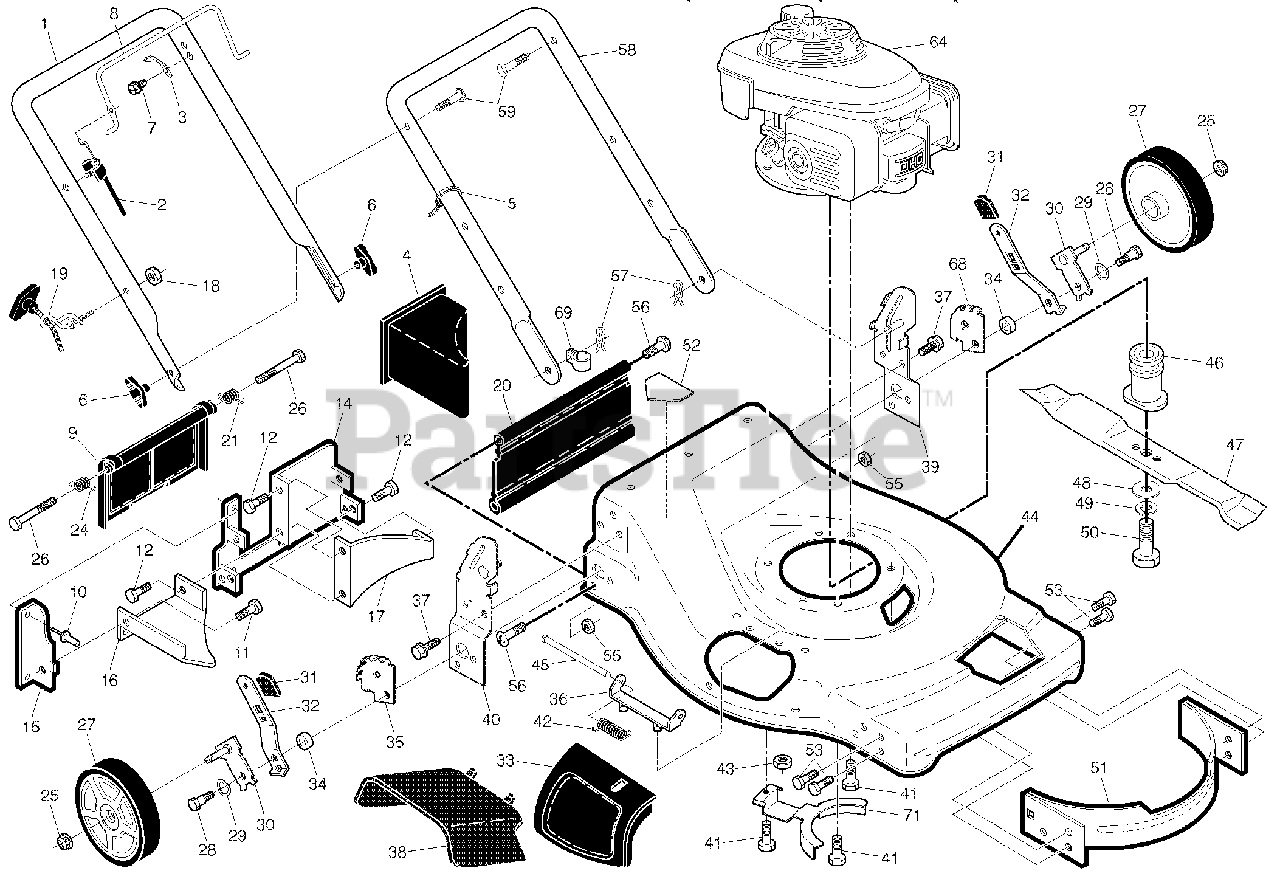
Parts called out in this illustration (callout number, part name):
1	UPPER HANDLE
2	Engine Zone Control Cable
3	Bracket, Upstop
4	MULCH PLUG
5	Wire Tie
6	Handle Knob
7	Hex Washer Head Screw
8	CONTROL BAR
9	Rear Door Assembly
10	Pop Rivet
11	Screw, Self-Tapping
12	SCREW, SEMS, HEX HEAD 1/4-20 X
14	Back Plate
15	Side Baffle
16	Discharge Baffle
17	Rear Baffle
18	Nut, Hex
19	Rope Guide
20	REAR SKIRT
21	Spring, Rear Door, LH
24	Spring, Rear Door, RH
25	Nut, Hex
26	Bolt, Rear Door
27	REAR WHEEL
28	Bolt, Shoulder 3/8-16 x 1
29	Washer, Curved, Cylindrical
30	AXLE ARM ASSEMBLY
31	Selector Knob
32	Selector Spring, Front
33	Mulcher Door
35	WHEEL ADJUSTING BRKT RH
36	Hinge Bracket Assembly
37	Screw, Sems, Thread Cutting 5/
38	Discharge Def ector
39	HANDLE BRACKET ASSEMBLY LH
40	HANDLE BRACKET ASSEMBLY RH
41	Screw, Hex Head, Threaded, Rol
42	Spring, Torsion
43	Locknut, Hex 1/4-20
44	Kit, Housing
45	Rod, Hinge
46	PULLEY, BLADE ADAPTER
48	Hardened Washer
49	Helical Lockwasher
50	Screw, Hex Head, Grade 8 3/8-2
51	Kit, Front Baffle
52	Danger Decal
53	SCREW.HEX.WASHEAD.1/4-20 X 3/8
55	NUT.CENTERLOCK.3/8-16 UNC.
56	Hinge Screw
57	Hairpin Cotter
58	LOWER HANDLE
59	Handle Bolt
68	WHEEL ADJUSTING BRKT LH
69	Clip, Cable
71	BELT KEEPER
